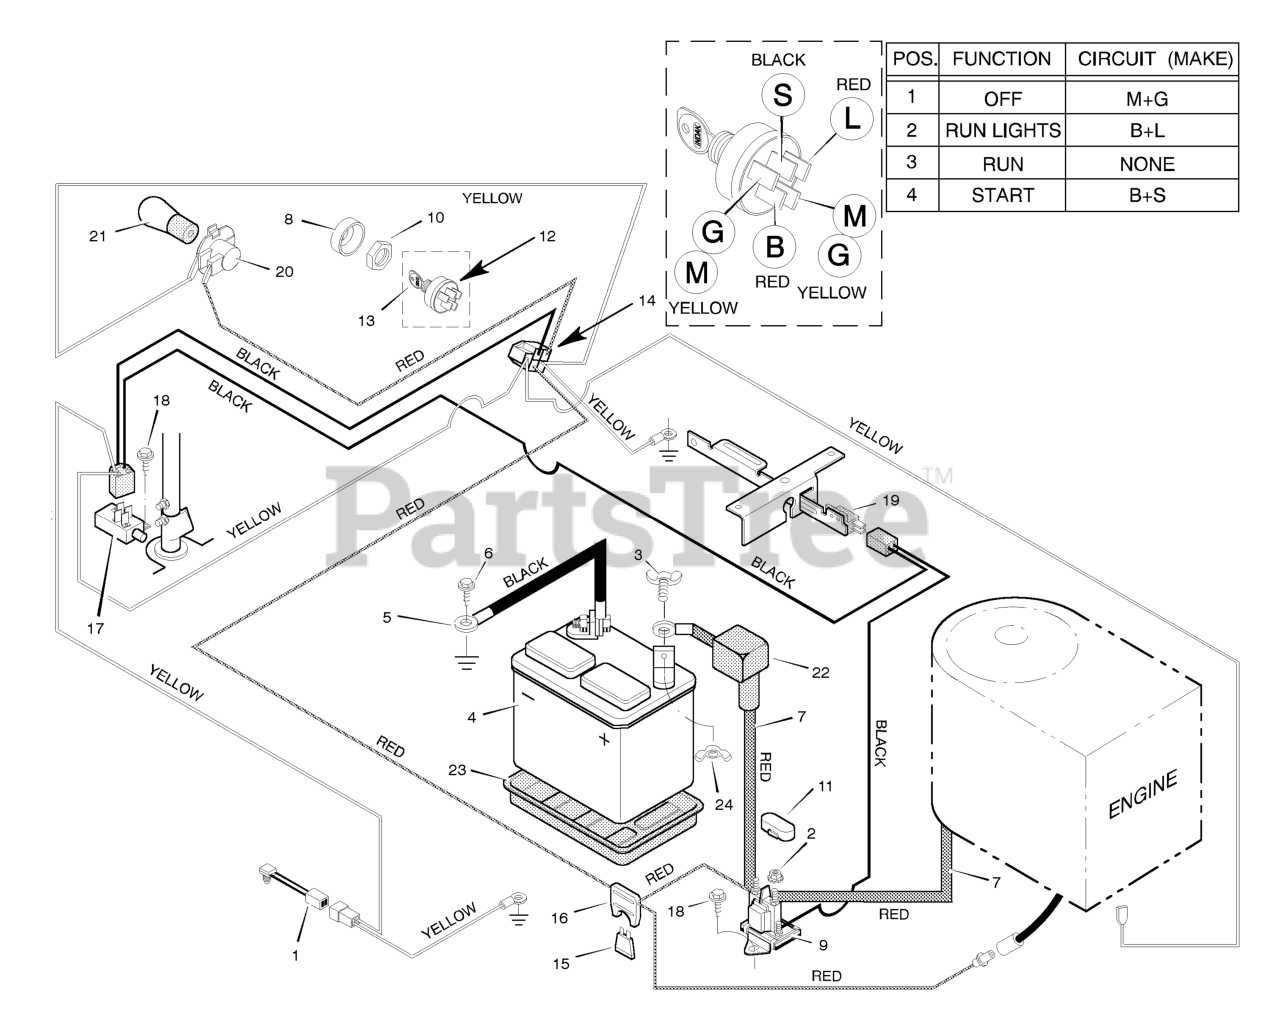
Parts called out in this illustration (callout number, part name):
1	Switch, Seat Sensor
2	Locknut
4	Battery
5	Cable, Battery Ground
7	Cable, Red Battery
8	Cap, Ignition
9	Solenoid
10	Nut, Hex
11	Cover, Solenoid
12	Switch, Ignition
13	Key, Ignition
14	Harness, Chassis Wire
16	Holder, Fuse
17	Switch, Limit
19	Switch, Limit
20	Socket, Light
21	Bulb, Light
22	Cover, Terminal
23	Tray, Battery
24	Wingnut
